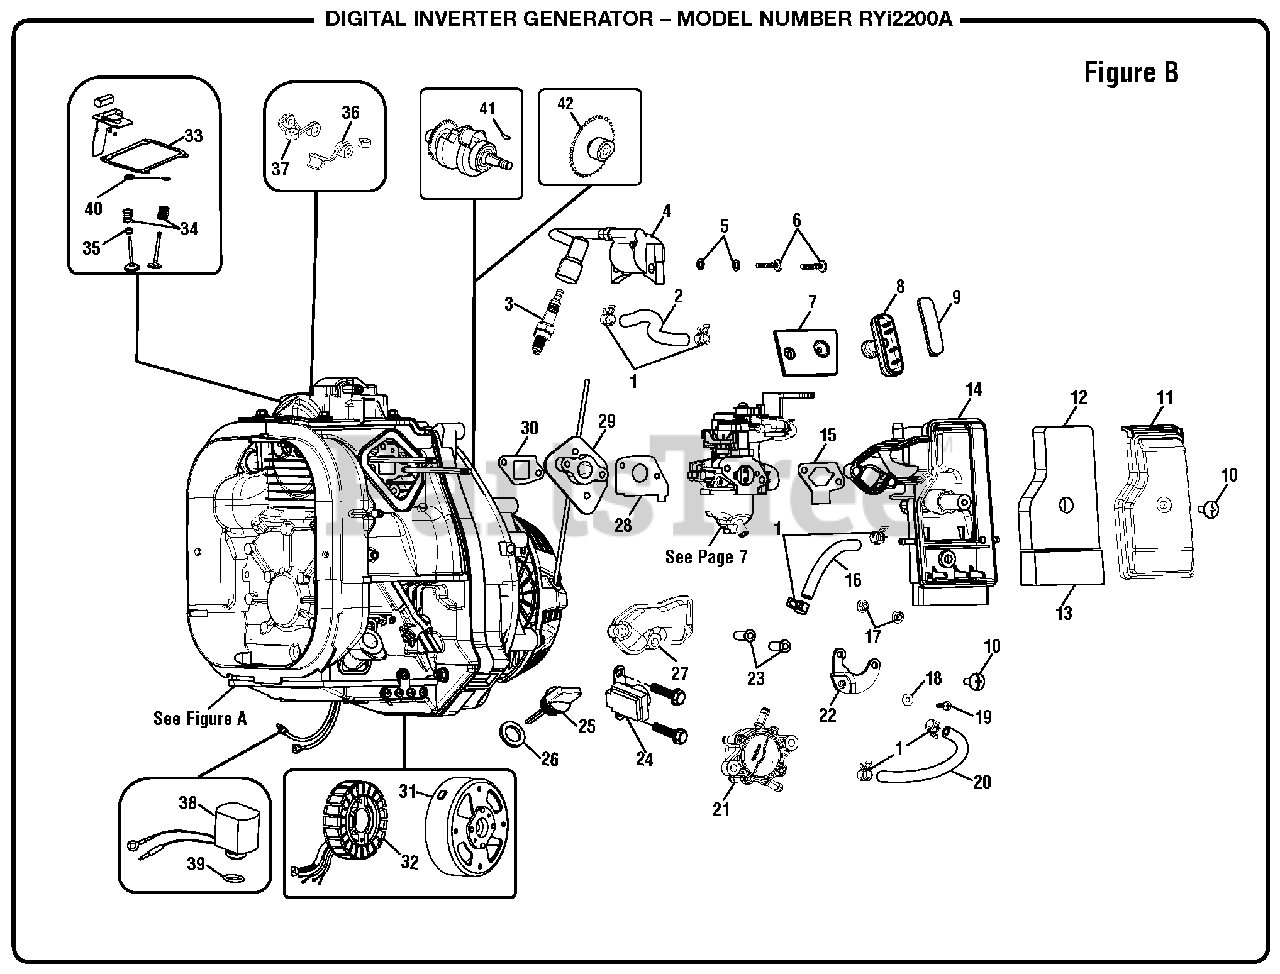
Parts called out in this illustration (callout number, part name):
1	Fuel Hose Clamp (9.5 mm)
2	Air Hose (3 Way Hose To Engine 180 mm)
3	Spark Plug (NHSP LD7RTS)
4	Ignition Coil
5	Washer (M5)
6	Screw (M4.8 x 19 mm)
7	Start Rope Cover
8	Recoil Handle
9	Handle Cover
10	Screw (M8 x 16 mm, Truss Hd.)
11	Air Cleaner Baffle
12	Air Cleaner Filter (Upper)
13	Air Cleaner Filter (Lower)
14	Air Cleaner Body
15	Intake Pipe Gasket
16	Fuel Hose (Fuel Pump To Fuel Valve, 95 mm)
17	Flange Nut (M5 x 0.8)
18	Washer (ID4.2 x OD10 x 1t)
19	Screw (M4.2 x 12 mm, Pan Hd.)
20	Fuel Hose (Engine To Fuel Pump, 140 mm)
21	Fuel Pump
22	Fuel Pump Bracket
23	Air Cleaner Body Nesting
24	Pick-up Coil
25	Engine Oil Dipstick
26	Oil Dipstick Seal
27	Intake Pipe Top Hood
28	Carburetor Gasket
29	Intake Seat
30	Insulating Board Gasket
31	Rotor Assembly
32	Stator Assembly
33	Head Gasket
34	Valve spring
36	Intake Rocker Assembly
37	Exhaust Rocker Assembly
38	Oil Sensor
39	Oil Sensor Seal
40	Valve Retainer
41	Engine Shaft Key
42	Engine Cam
